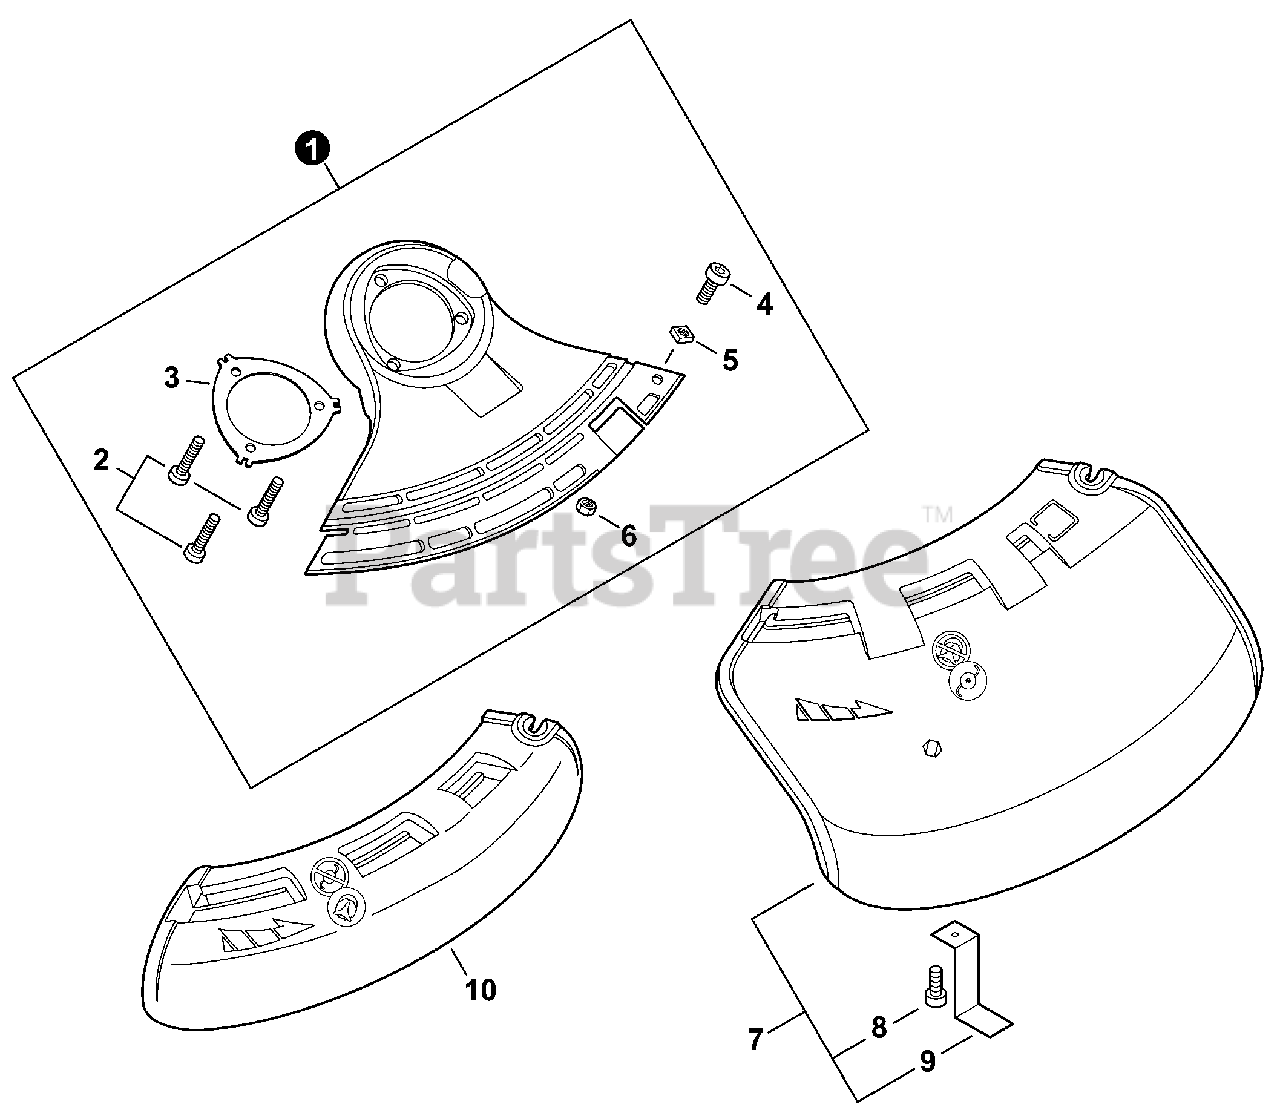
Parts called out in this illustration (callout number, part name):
1	DEBRIS SHIELD BASE ASSY
2	BOLT, TORX 5×16
3	PLATE, SHIELD
4	BOLT, TORX 5×25
5	NUT M5
6	NUT, LOCK
7	DEBRIS SHIELD ASSY - TRIMMER EXTENSION
8	BOLT, TORX 5×16
9	CUTTER, LINE
10	SHIELD, DEBRIS - BLADE EXTENSION
